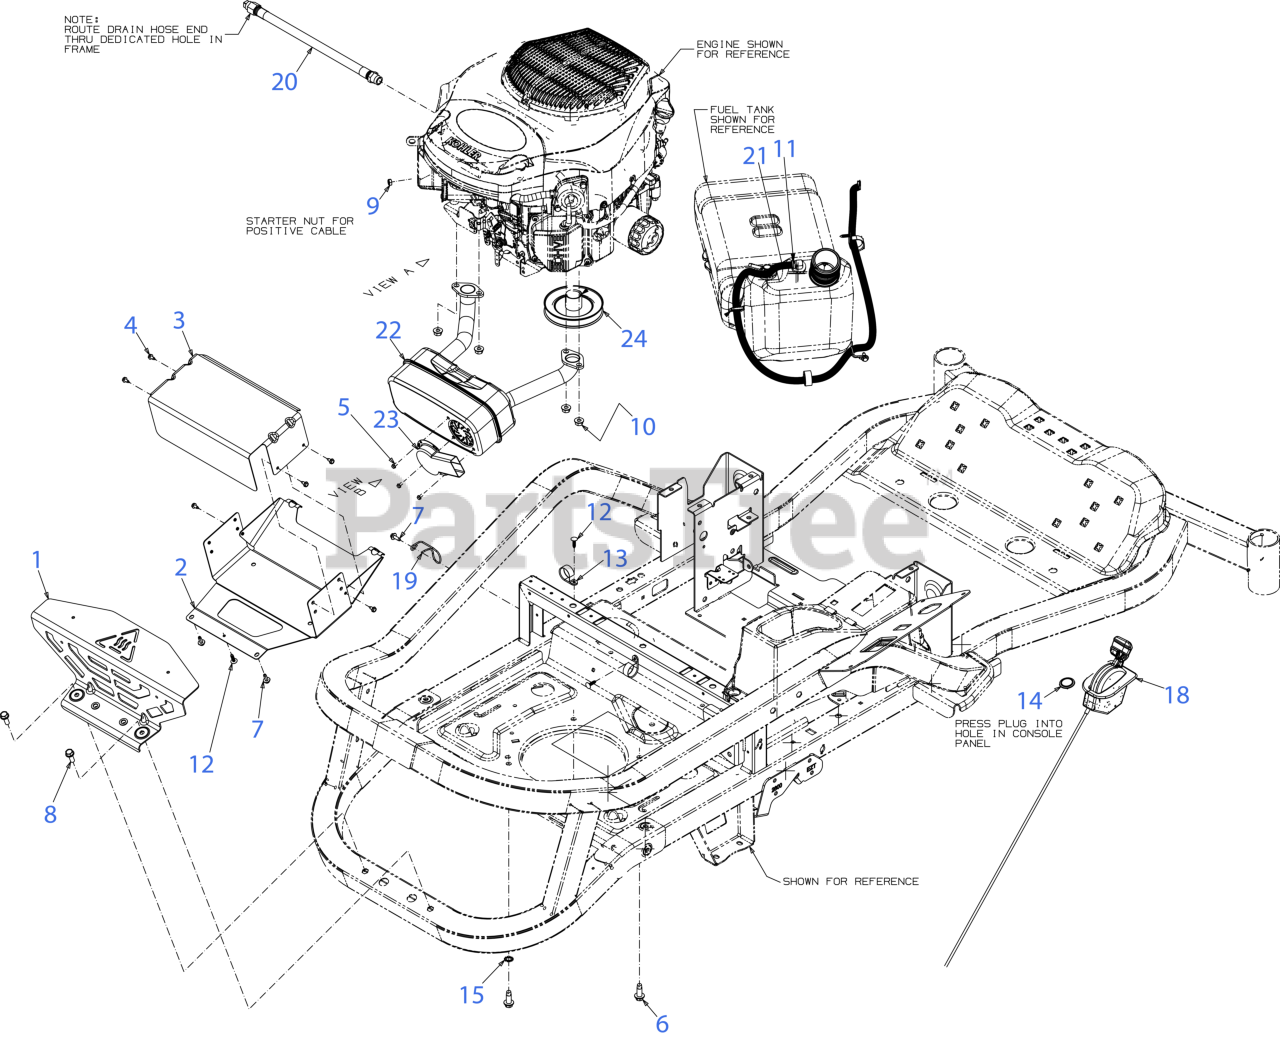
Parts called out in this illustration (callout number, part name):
1	MUFFLER COVER (REAR) (BLACK)
2	MUFFLER SHIELD (LOWER)
3	MUFFLER SHIELD (TOP)
4	HEX SCREW AB-TAP #10 x .50
5	HEX SCREW WASHER HD #8-18 x 0.500
6	SCREW 3/8-16 x 1
7	SCREW M6-1 x .625
8	SCREW 5/16-18 x .875 GR5
9	HEX NUT 1/4-20
10	HEX FLANGE NUT M8X
11	HOSE CLAMP 1/20
12	RATCHET CLIP (.188 x .85)
13	DRAIN HOSE CLAMP
14	CHOKE PLUG
15	LOCK WASHER 3/8
18	THROTTLE CABLE 51.0LG
19	HOSE GUIDE
20	OIL DRAIN HOSE
21	FUEL HOSE LOW PERMEATION 45"
22	EXHAUST MUFFLER (KH TWIN)
23	EXHAUST DELECTOR (LONG)
24	TRANSMISSION DRIVE PULLEY
